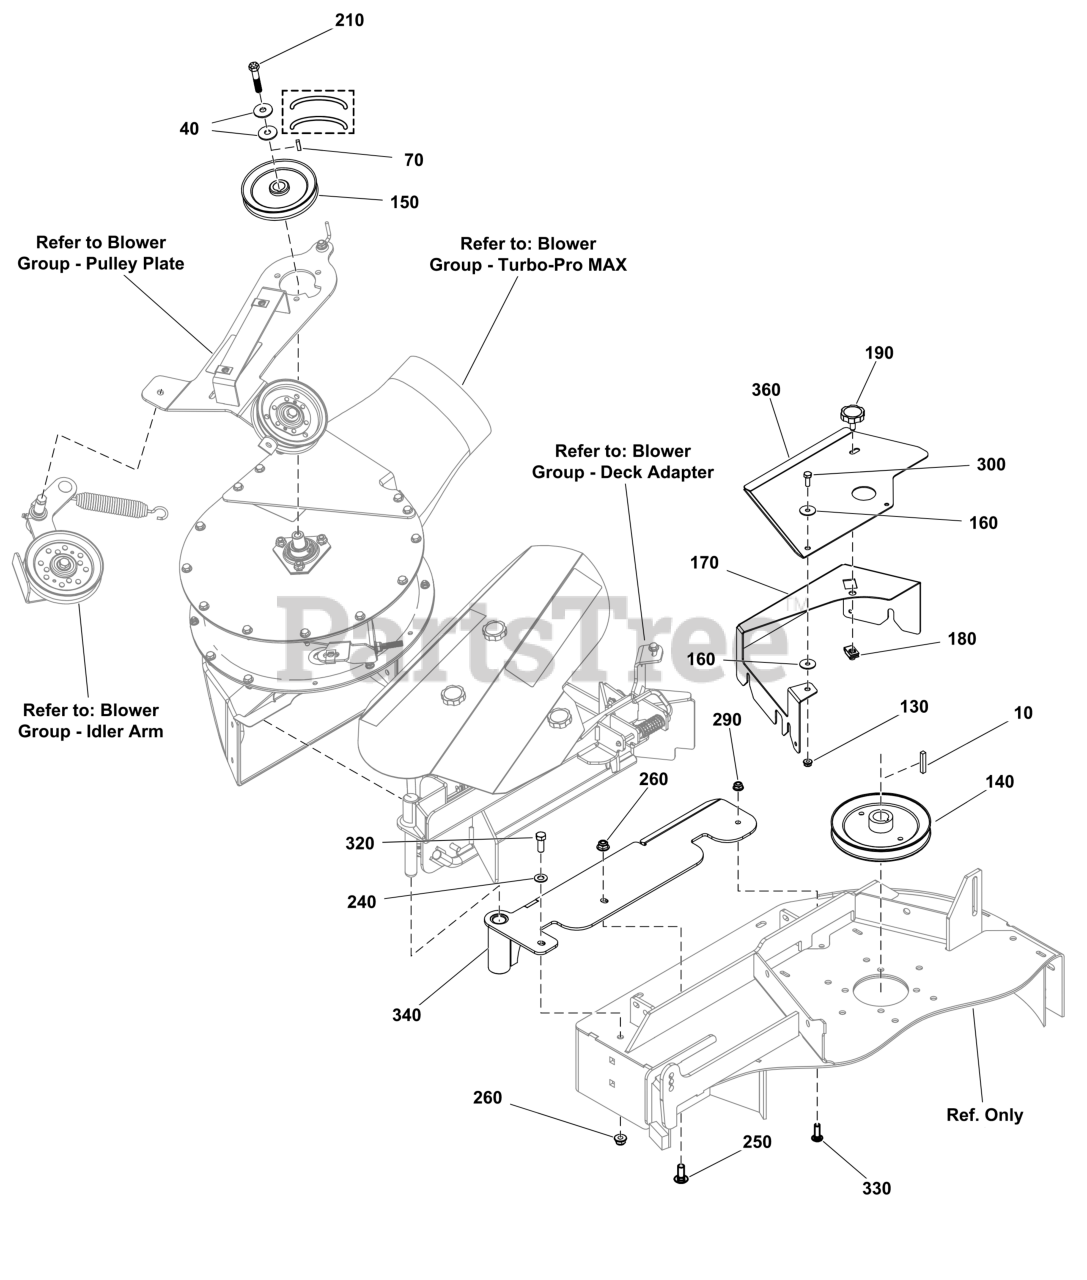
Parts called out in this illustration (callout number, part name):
10	KEY 1/4 SQ X 1 1/2
40	WASHER, BEVELED
70	KEY, SQUARE
140	PULLEY, Spindle
160	WASHER, 1/4 FENDER
170	GUARD, Pulley
180	BODY CLIP, 5/16-18 X
190	KNOB, 5/616-18 X 1
210	BOLT
250	BOLT, RD HD, 3/8-16X1
260	NUT, 3/8-16 HEX NYLOCK
290	NUT
300	BOLT, 1/4-20 X 3/4" G
320	BOLT, 3/8-16 X 1" GD5
330	BOLT, 5/16-18 X 1", C
360	SHIELD, Belt
